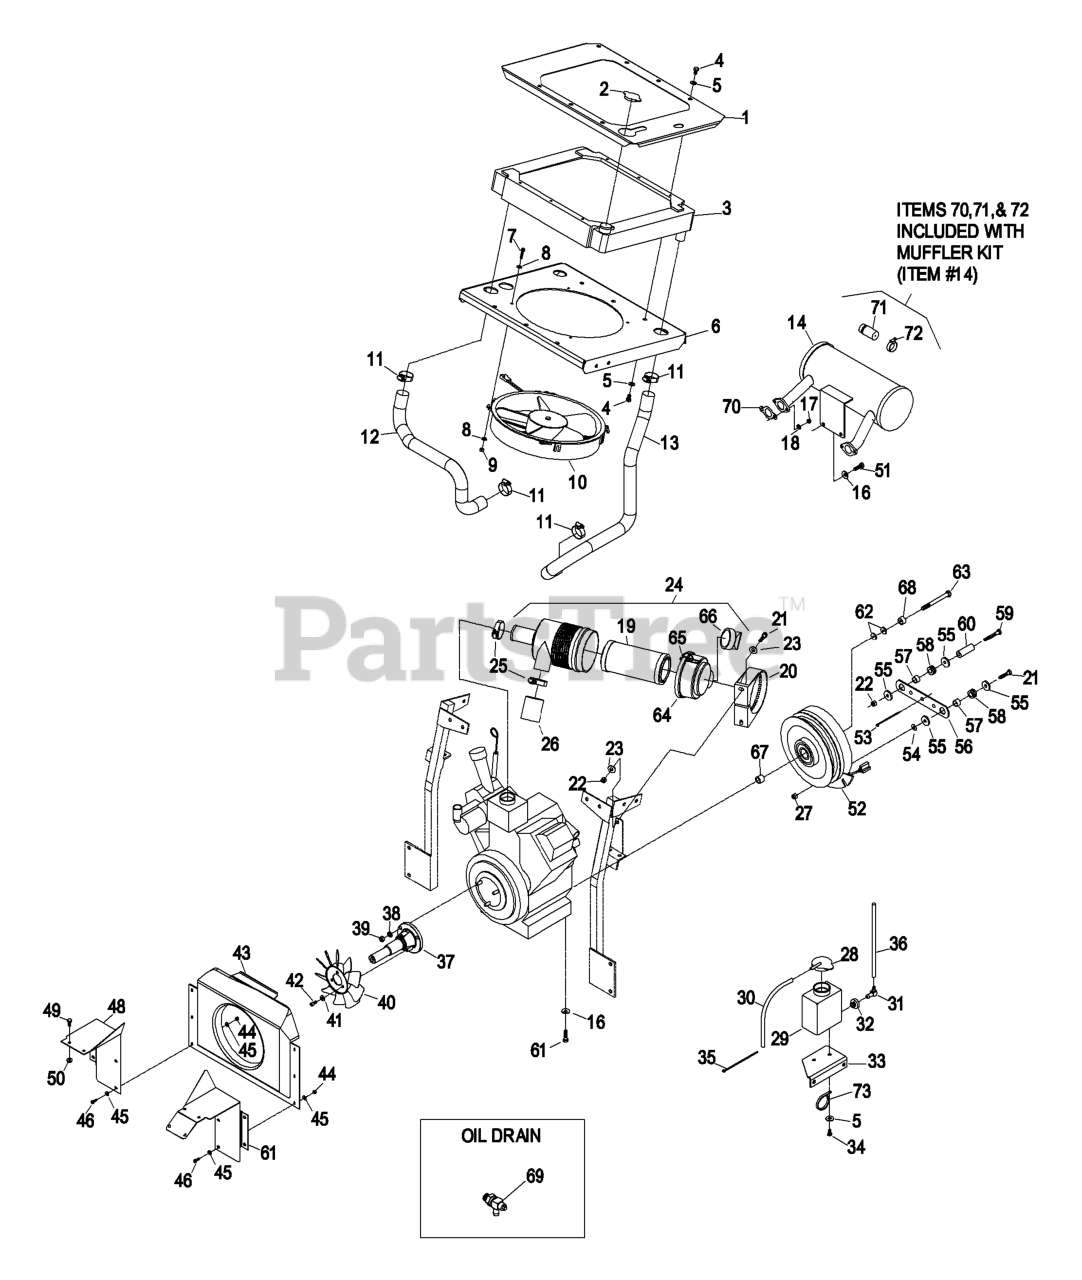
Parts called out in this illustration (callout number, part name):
2	CAP-RADIATOR
3	RADIATOR-MOUNT
4	SCREW-HH
5	WASHER-PLAIN
8	WASHER-FLAT
9	NUT-LOCK, HH
12	HOSE-INLET, RADIATOR
13	HOSE-OUTLET, RADIATOR
14	KIT,MUFFLER W/ARRESTOR
16	WASHER-BELLEVILLE
17	NUT-HEX
18	WASHER-LOCK
20	BRACKET-MOUNTING
21	SCREW-HH
22	NUT-LOCK, NI
23	WASHER-FLAT
24	AIR CLEANER ASM
25	CLAMP-HOSE
26	HOSE-INLET, AIR
28	CAP-TANK, OVERFLOW
29	TANK-OVERFLOW
34	SCREW-HH
35	TIE-CABLE
37	EXTENSION-CRANKSHAFT
38	WASHER-LOCK
39	NUT-HEX
40	FAN-PUMP, COOLING
41	WASHER-FLAT
42	SCREW-HSH
43	SHROUD-FAN, HYD
44	NUT-LOCK, NI
45	WASHER-FLAT
46	SCREW-PPH
47	SHIELD-LH
49	SCREW-HH
51	SCREW-HH
53	TIE-PLASTIC
54	WASHER-FLAT
56	STRAP-CLUTCH, BRAKE
58	GROMMET
59	SCREW-HH
60	SPACER-ANCHOR, CLUTCH
61	SCREW-HH
62	WASHER-SPRING
63	SCREW-HH
64	COVER ASM
65	LATCH-CLEANER, AIR
66	VALVE-VACUATOR
67	SPACER-CLUTCH
68	KEEPER-CLUTCH
69	VALVE, OIL DRAIN
70	GASKET-EXHAUST
71	ARRESTOR-SPARK
72	CLAMP-MUFFLER
73	CLIP-LOOM
